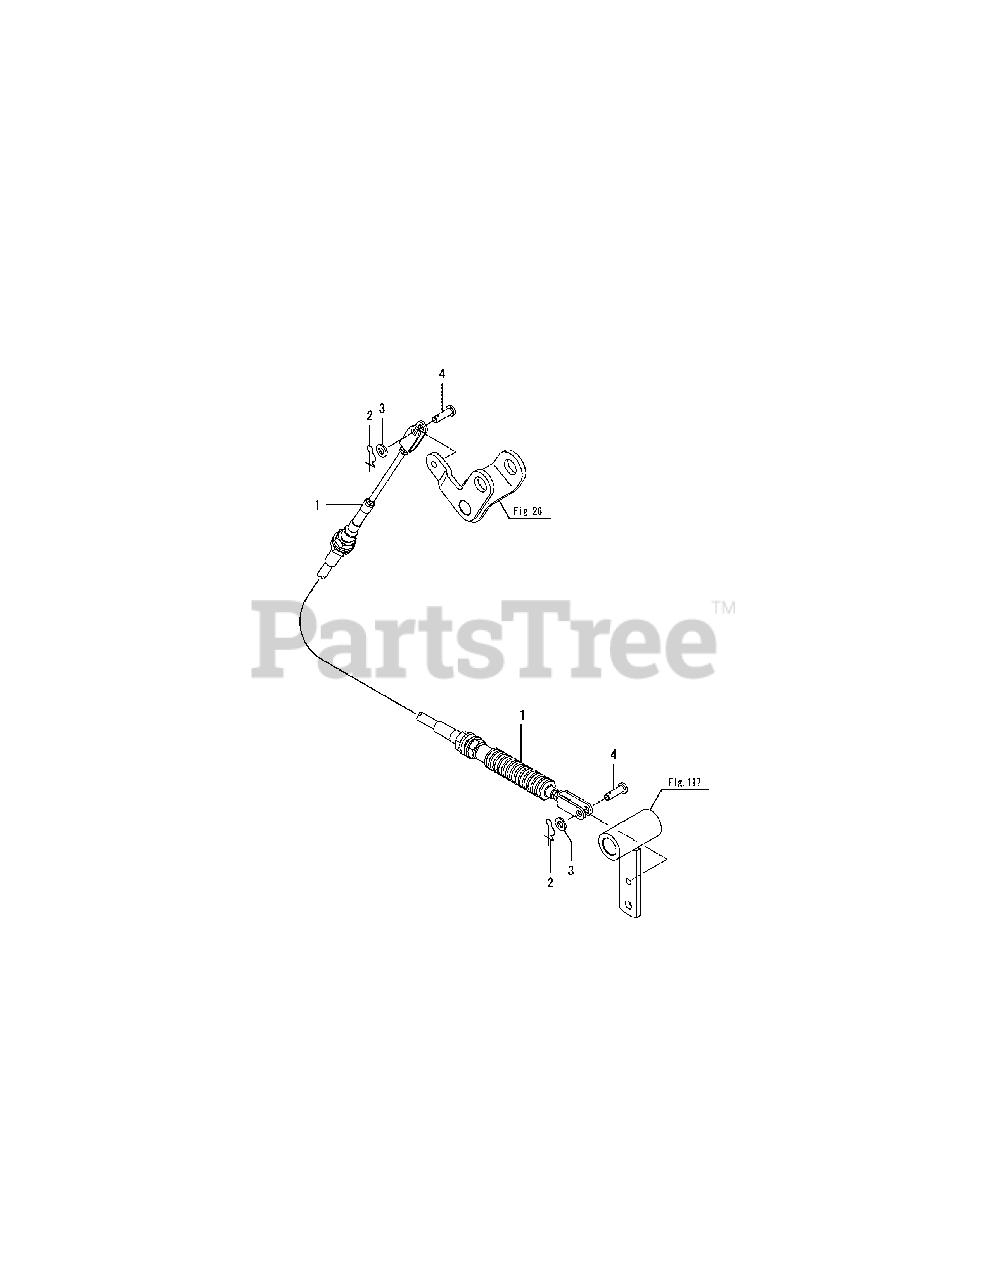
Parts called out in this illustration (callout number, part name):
1	CABLE, REVERSER
2	PIN 6, COME-OFF SNAP
3	WASHER 6, POLISHED
